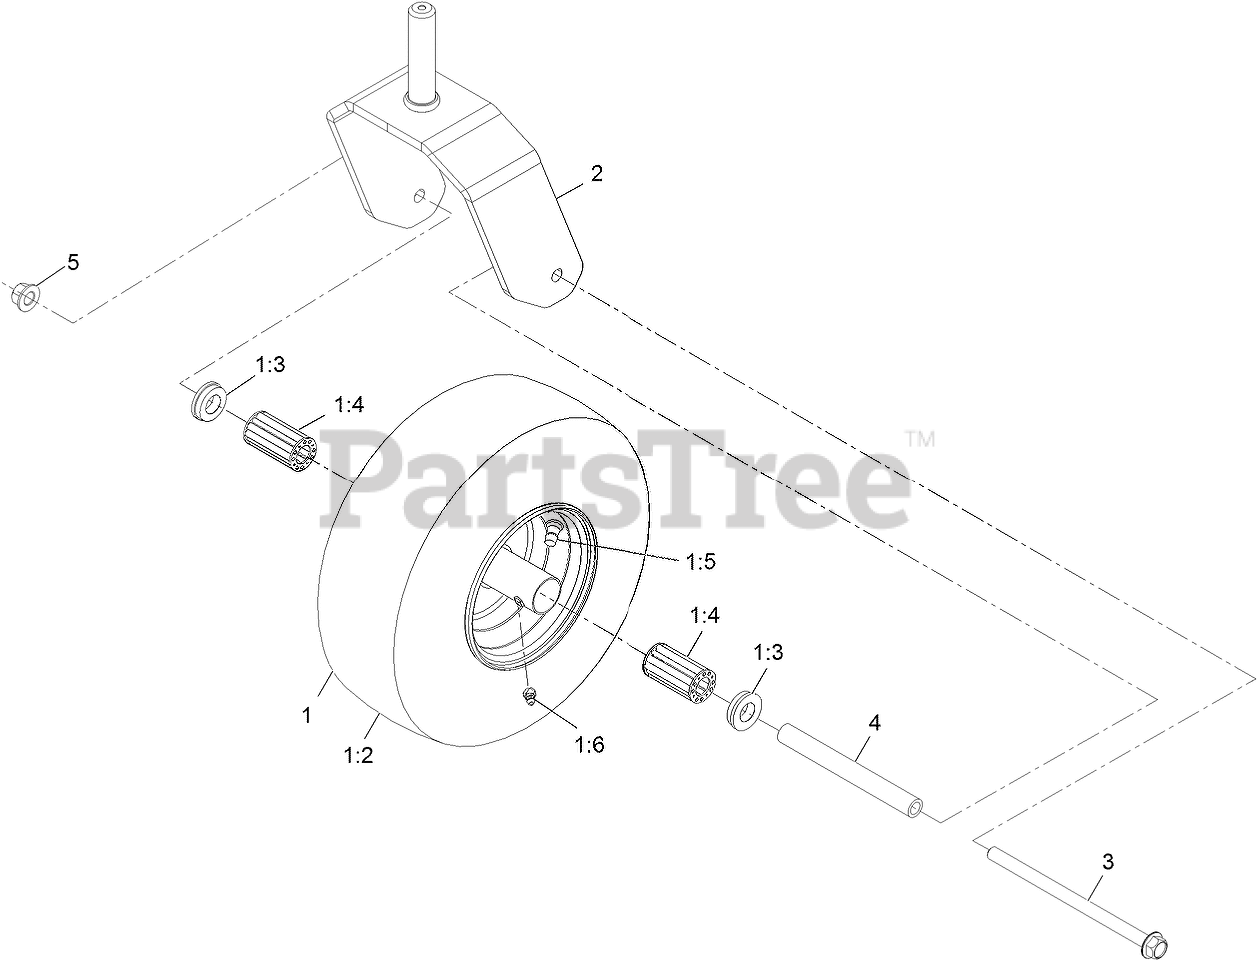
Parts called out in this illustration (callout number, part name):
1	ASM-WHEEL AND TIRE 13X6.50-6
1:3	BUSHING-FLANGE
1:4	BEARING-ROLLER, WHEEL
1:5	VALVE
1:6	FITTING-ZERK
2	FORK-CASTER
3	SCREW-HHF
4	SPANNER-WHEEL, CASTER
5	Nut-Lock 1/2-13
